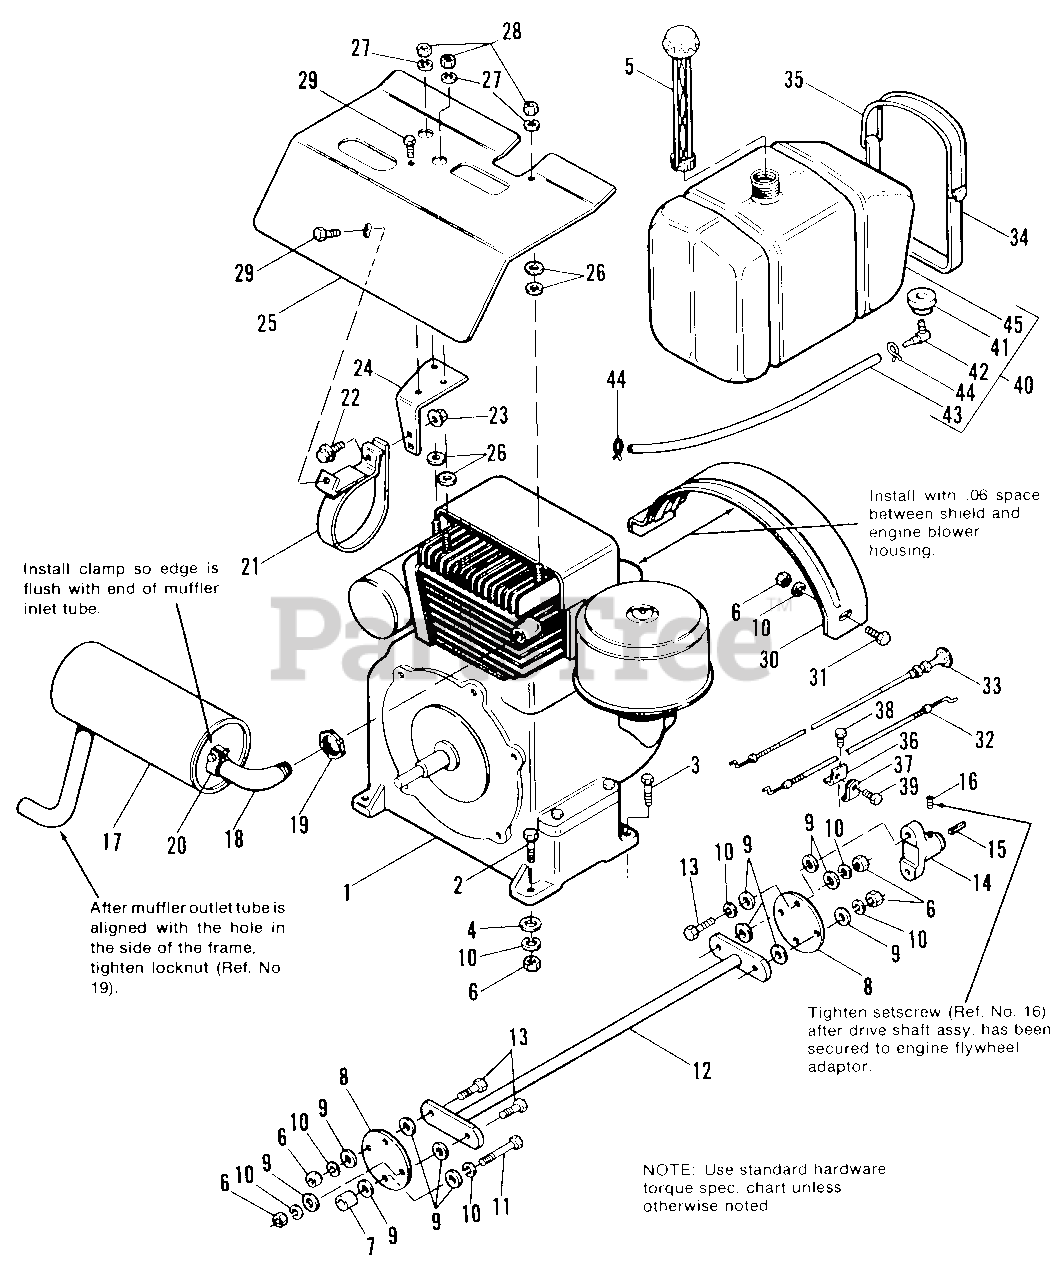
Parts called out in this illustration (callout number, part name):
1	ENGINE, 16 H.P. Briggs & Stratton
2	CAPSCREW, Hex Hd., 3/8-16 x 1-1/2
3	CAPSCREW, Hex Hd., 3/8-16 x 1-5/16
4	WASHER, 3/8
5	CAP, Fuel Tank, Gauge
6	NUT, Hex, 3/8-16
9	WASHER, Special
10	LOCKWASH ER, 3/8
11	CAPSCREW, Hex Hd., 3/8-16 x 2-1/4
12	SHAFT ASSY., Drive
13	CAPSCREW, Hex Hd., 3/8-16 x 1-1/4
14	FLANGE, Drive Shaft
15	KEY, Drive Shaft
16	SETSCREW. 3/8-24 x 3/8
17	MUFFLER, Exhaust
18	ELBOW ASSY., Exhaust
20	CLAMP, Muffler
21	STRAP ASSY., Muffler
22	CAPSCREW, Hex, Flange, Whizlock 5/16-18 x 1-1/2
23	LOCKNUT, Hex, Flange, Whiz, 5/16-18
24	SUPPORT, Muffler
25	SHIELD, Heat
26	WASHER, 5/16
27	LOCKWASHER, 5/16
28	NUT, Hex, 5/16-18
29	SCREW, Hex Hd., Taptite, 1/4-20 x 1/2
31	CAPSCREW, Hex Hd., 3/8-16 x 3/4
32	CONTROL, Throttle
33	CONTROL, Choke
34	STRAP, Tank
35	STRAP, Fuel Tank
36	BRACKET, Cable
37	CLIP, Bowden Wire
38	SCREW, Hex Hd., 1/4-20 x 5/8
39	SCREW, Taptite #10-24 x 1/2
40	TANK ASSY., Fuel
44	CLAMP, Hose
